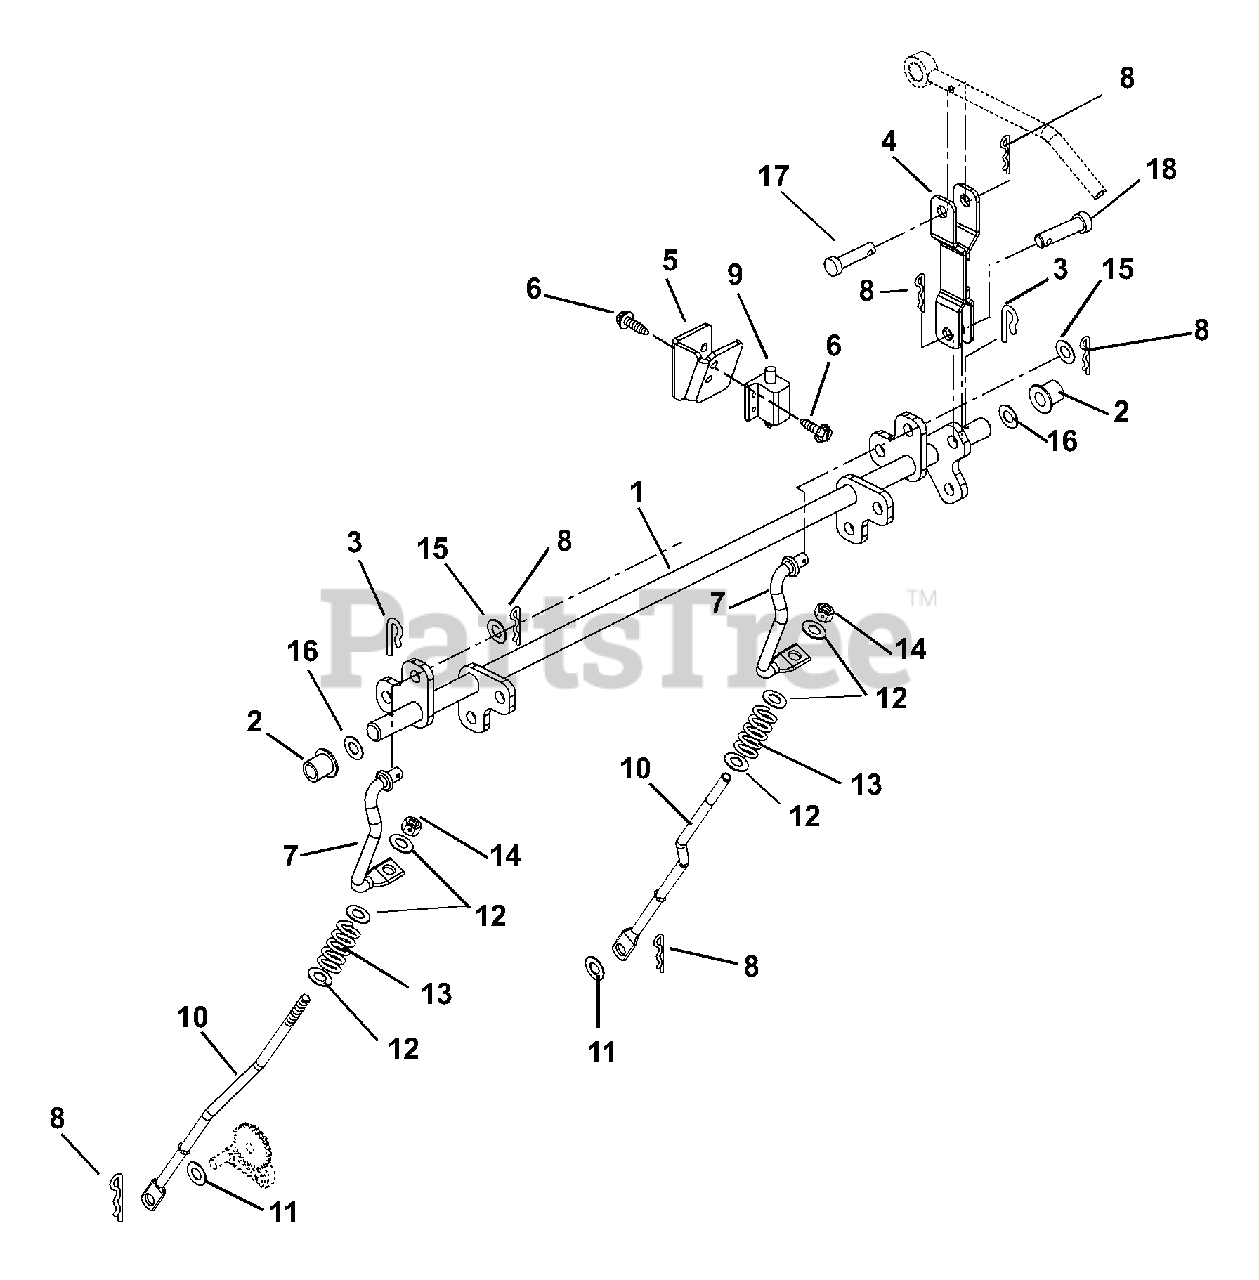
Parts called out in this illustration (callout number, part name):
1	WMT, BRAKE ROD
2	BSHG-FLG .630X1.000X.625 NY
3	PIN, SPRING CLIP
4	CLEVIS WELDMENT
5	BRACKET, BRAKE SWITCH
6	@SCR-TAP 10-24X.50 HWH TR YWZC
7	ROD-OVER CENTER
8	PIN-HAIR, ENDRIES #25 YWZC
9	SWITCH- DOUBLE POLE N.O./N.O.
10	ROD, PARK BRAKE IZT
11	WSHR-FL-STL .406X1.00X.188 YWZ
12	@WSHR-FL-STL.344X.688X.065YWZC
13	SPRING, COMPRESSION
14	@NUT-LK-NYL .312-18 YWZC
15	@WSHR-FL-STL.406X.812X.065 YWZ
16	WSHR-FL-STL .627X.990X.032
17	PIN-CLEV .370X1.50
18	PIN-CLEV .375X.948 YWZC
